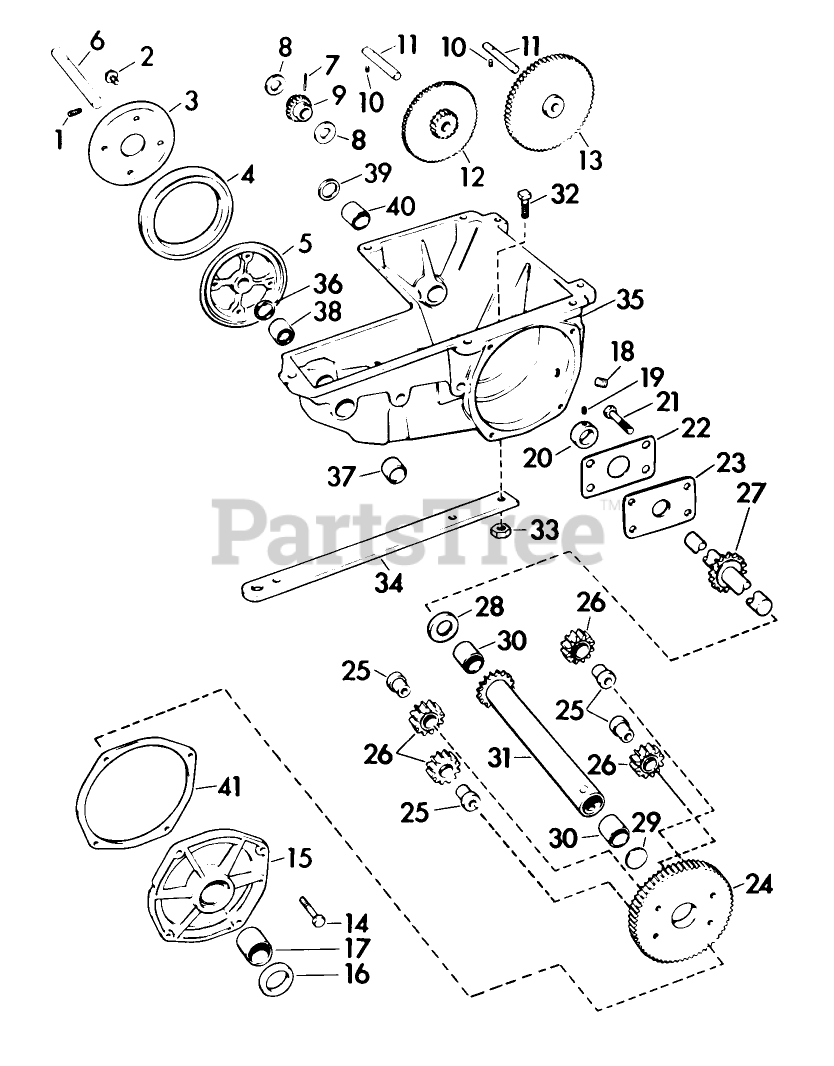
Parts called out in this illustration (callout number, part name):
10	SET SCREW
21	Screw-Differential
24	Gear-Reduction (No. 3)
26	Gear-Planet, Differential
34	Bar-Draw
